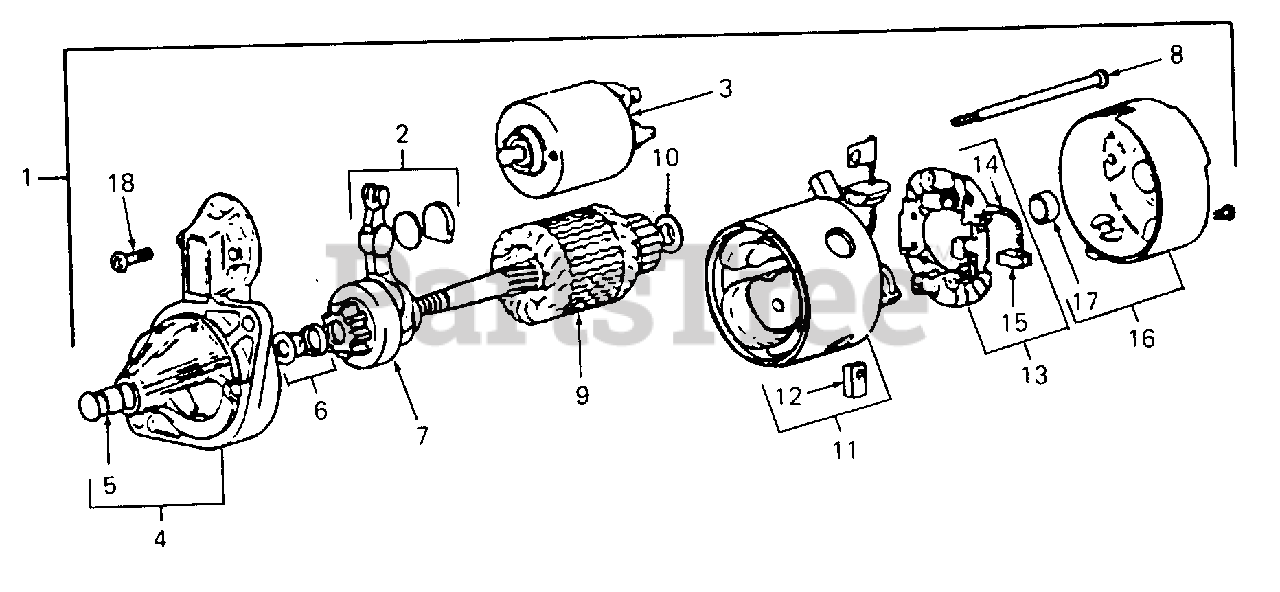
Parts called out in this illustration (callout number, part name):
1	Starter Assy
3	Switch, Magnetic
4	Frame, Drive End
7	Clutch, Over Running
10	Washer, Adjusting
13	Holder, Brush
14	Spring, Brush
18	Screw, Pan Head
